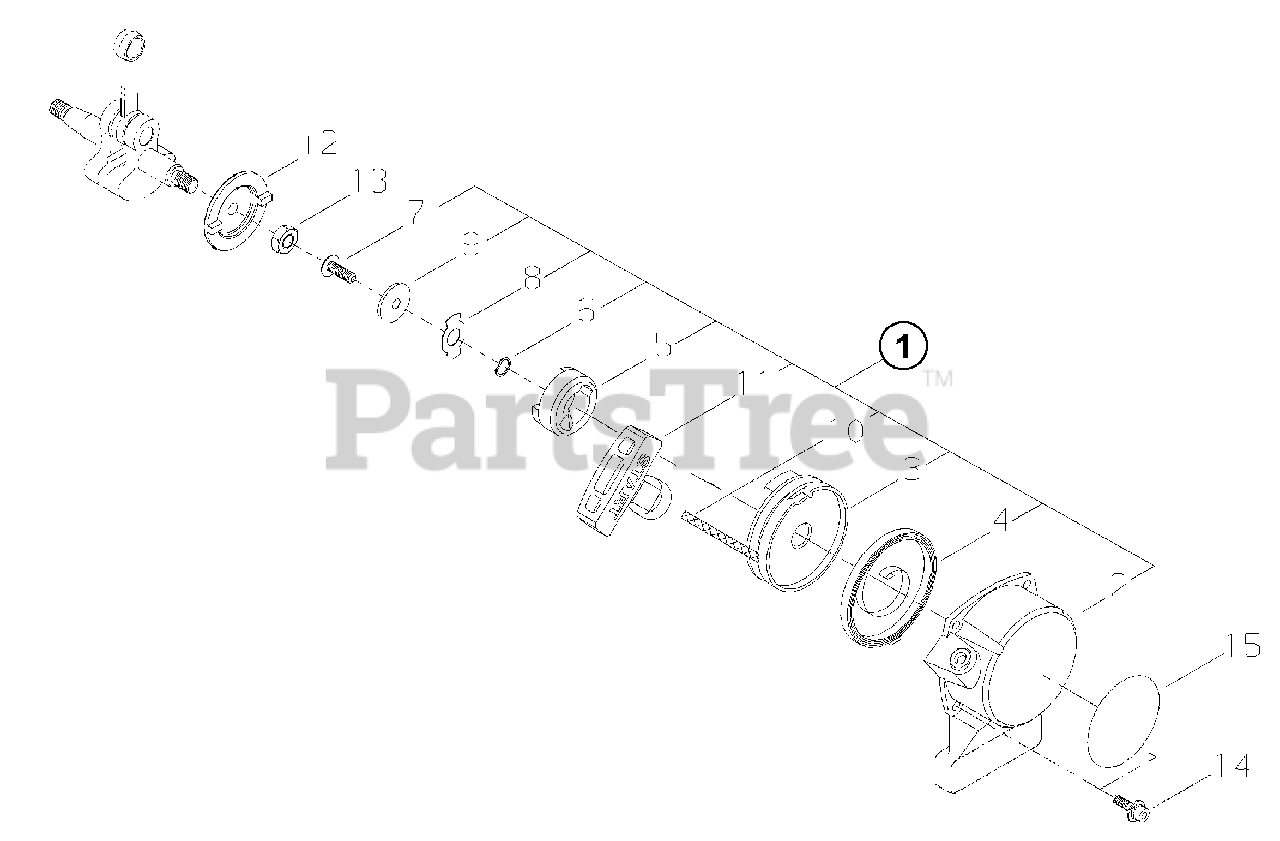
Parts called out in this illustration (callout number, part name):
1	STARTER ASSY, RECOIL
2	CASE, RECOIL STARTER
3	REEL, ROPE
4	SPRING, RECOIL
5	PAWL, STARTER
6	WASHER, WAVE
7	SCREW 5 MM
8	RETAINER
9	WASHER 5 MM
10	ROPE, STARTER
11	GRIP, STARTER
12	PULLEY, STARTER
13	NUT M8×1
14	BOLT M4×16
15	LABEL, RECOIL C4
